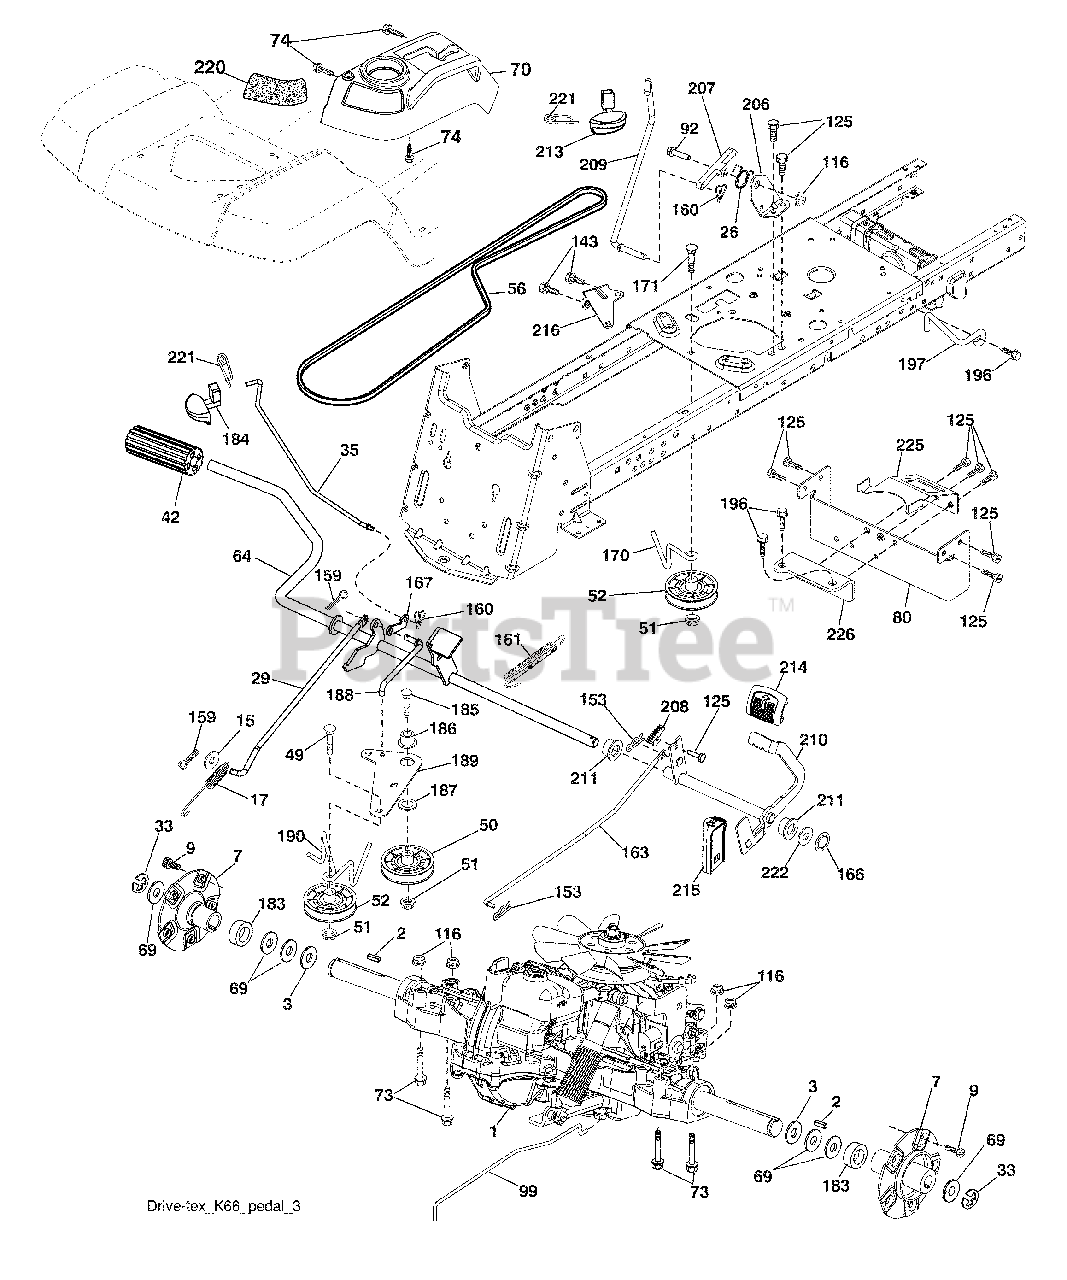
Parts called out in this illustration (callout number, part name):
1	Transaxle, TuffTorq K66 Y
3	Hardened Washer
7	Hub Asm. Wheel
9	Bolt Hub Wheel
15	Washer 13/32 x 13/16 x 16 Ga.
17	Spring, Brake
26	Spring Return Cruise
29	Rod, Brake
35	Rod, Brake, Park
42	Cover, Foot Pedal
50	Pulley Idler Flat
51	Lock Nut 3/8-16
52	Idler V-Groove 910" Offset
56	V-Belt, Drive
64	Shaft Asm. Pedal Brake Control
69	Washer 1 1/32 x 1 5/8 x 16 Ga.
70	Console Asm.
73	Bolt Hex Flghd 5/16-18 Gr. 5
74	Screw Hx Wsh Hi-Lo 1/4 x 1/2 unc
80	Strap Torque
92	Bolt Fin Hex 5/16-18 unc x 1.25
99	Rod Bypass
116	Nut Lock Hex Flange 5/16-18
125	Screw 5/16-18 x 3/4
143	Screw 5/16-18 x 1/2
153	Retainer Spring
159	Pin Cotter 1/8 x 3/4
160	Retainer Clip
161	Spring, Return, Clutch
163	Rod Pedal Control
166	Nut Push .625
167	Latch Brake Parking
170	Keeper Belt Centerspan
183	Spacer Axle
184	Handle Parking Brake
186	Spacer Retainer
187	Washer
188	Link Clutch Ground Drive
189	Bellcrank Ground Drive
190	Keeper Bellcrank Ground Drive
196	Screw 3/8-16 x 1
197	Bracket Clutch Anti-Rotation
206	Bracket Mount Latch Cruise
207	Latch Control Cruise
208	Gear Sector Control Cruise
209	Rod Control Cruise
210	Rocker Asm Cruise
211	Bearing Nylon
213	Handle Parking Brake
214	Pedal Forward
215	Pedal Reverse
216	Bracket Pulley Idler
220	Reflector RH
221	Retainer Spring Clip Handle
222	Washer 21/32 x 1-1/4 10 Ga.
225	Keeper Belt Trans.
226	Bracket Mount Torque
